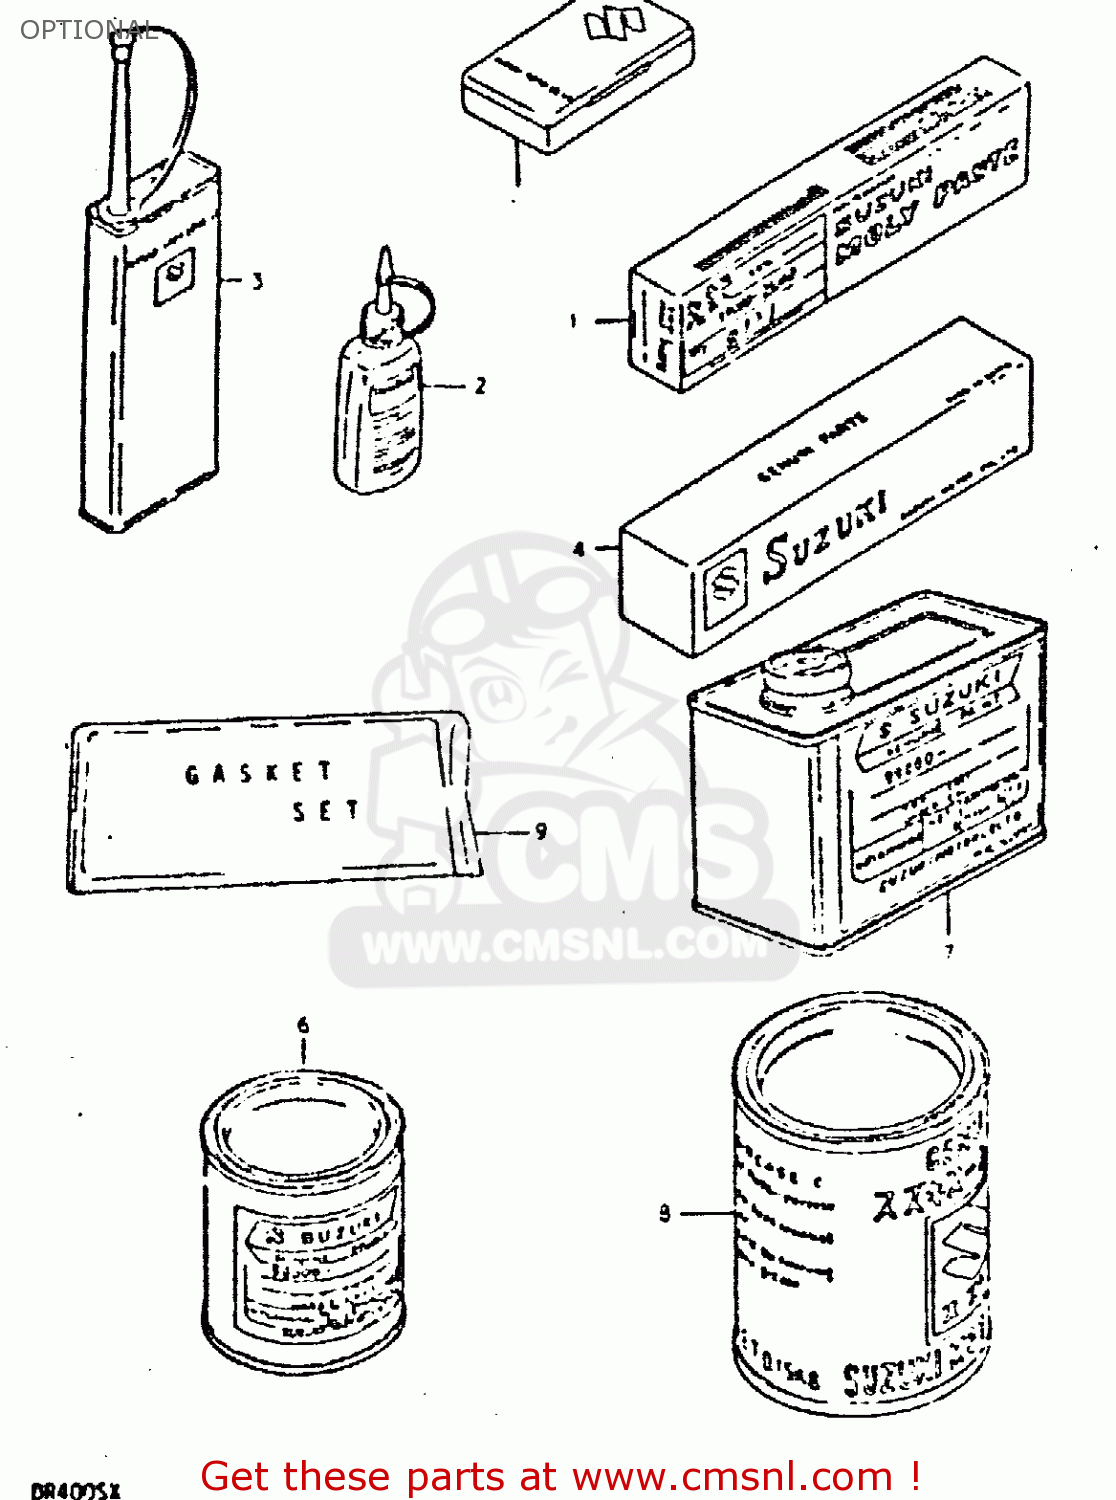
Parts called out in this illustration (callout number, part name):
1	SUZUKI MOLY PASTE
2	THREAD LOCK NO.1342
3	THREAD LOCK NO.1401 CLEAR 200G
4	LIQUID GSKT NO.1211 100G WHITE
5	TUBE REPARING TOOL
6	PAINT,BLACK
7	PAINT (BLACK)
8	GREASE(C)EP2 LITHIUM 150G
9	GASKET SET
